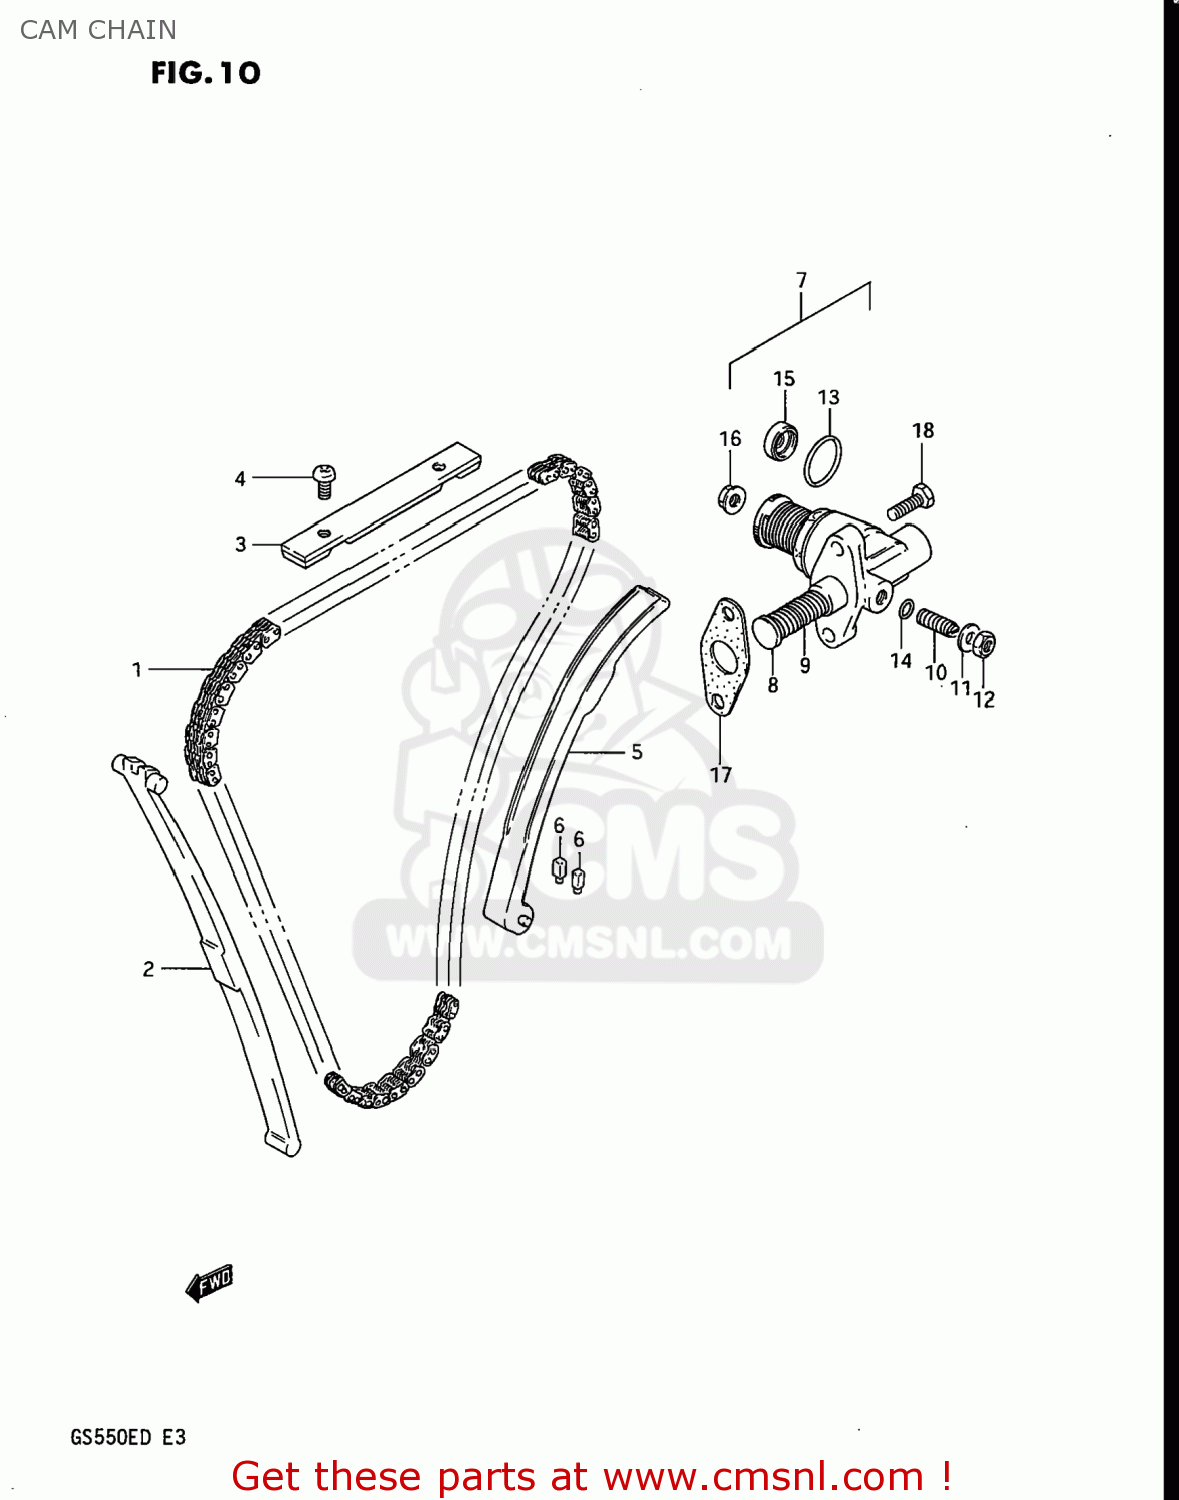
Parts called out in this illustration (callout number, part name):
1	CHAIN,CAMSHAFT DRIVE
2	GUIDE,CAM CHAIN NO.1
3	GUIDE,CAM CHAIN NO.2
4	SCREW
5	TENSIONER,CAM CHAIN
6	CUSHION,CAM CHAIN TENSIONER
7	ADJUSTER ASSY,TENSIONER
8	ROD,PUSH
9	SPRING
10	SCREW,TENSIONER ADJUST
11	WASHER,8.5X16X
12	NUT
13	O-RING
14	O-RING
15	OIL SEAL
16	NUT
17	GASKET,TENSIONER ADJUSTER (MCA)
18	SCREW
